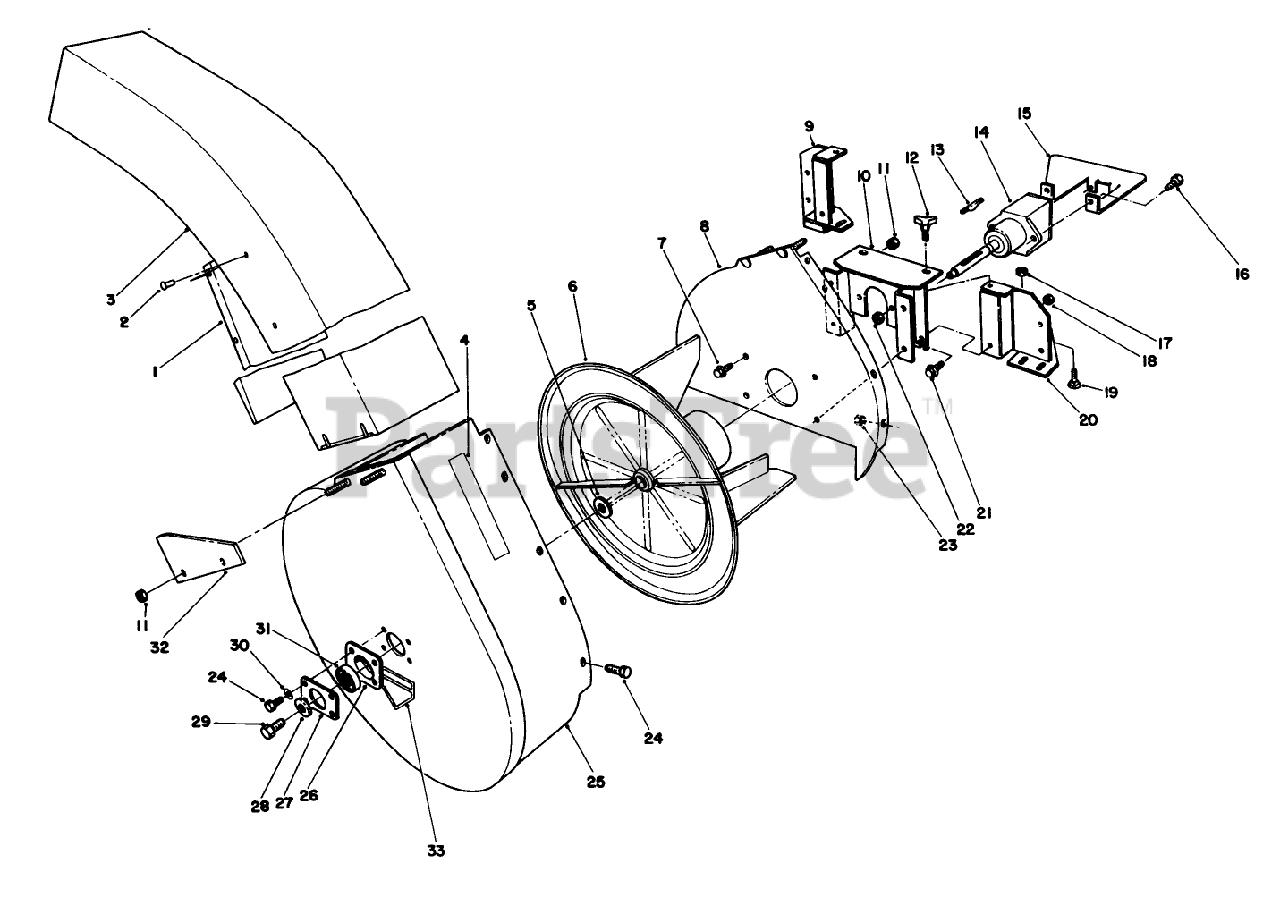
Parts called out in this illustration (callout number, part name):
3	CHUTE ASM
5	SPACER-BEARING
7	SCREW-HHF
9	L/H BLOWER MT/NUT ASM
11	NUT-LOCK, NI
16	SCREW-HH
17	NUT-KEPS
18	NUT-JAM
19	SCREW-CARR
20	RH BLWR MT BRKT WA
21	SCREW-HHF
22	NUT-LOCK, NI
23	NUT-LOCK, NI
24	SCREW-HH
25	BLOWER HOUSING ASM
26	CUP-BEARING
28	SPACER
29	SCREW-HH, LOCK
30	SCREW-HH
31	BEARING-BALL
33	DECAL-DANGER
